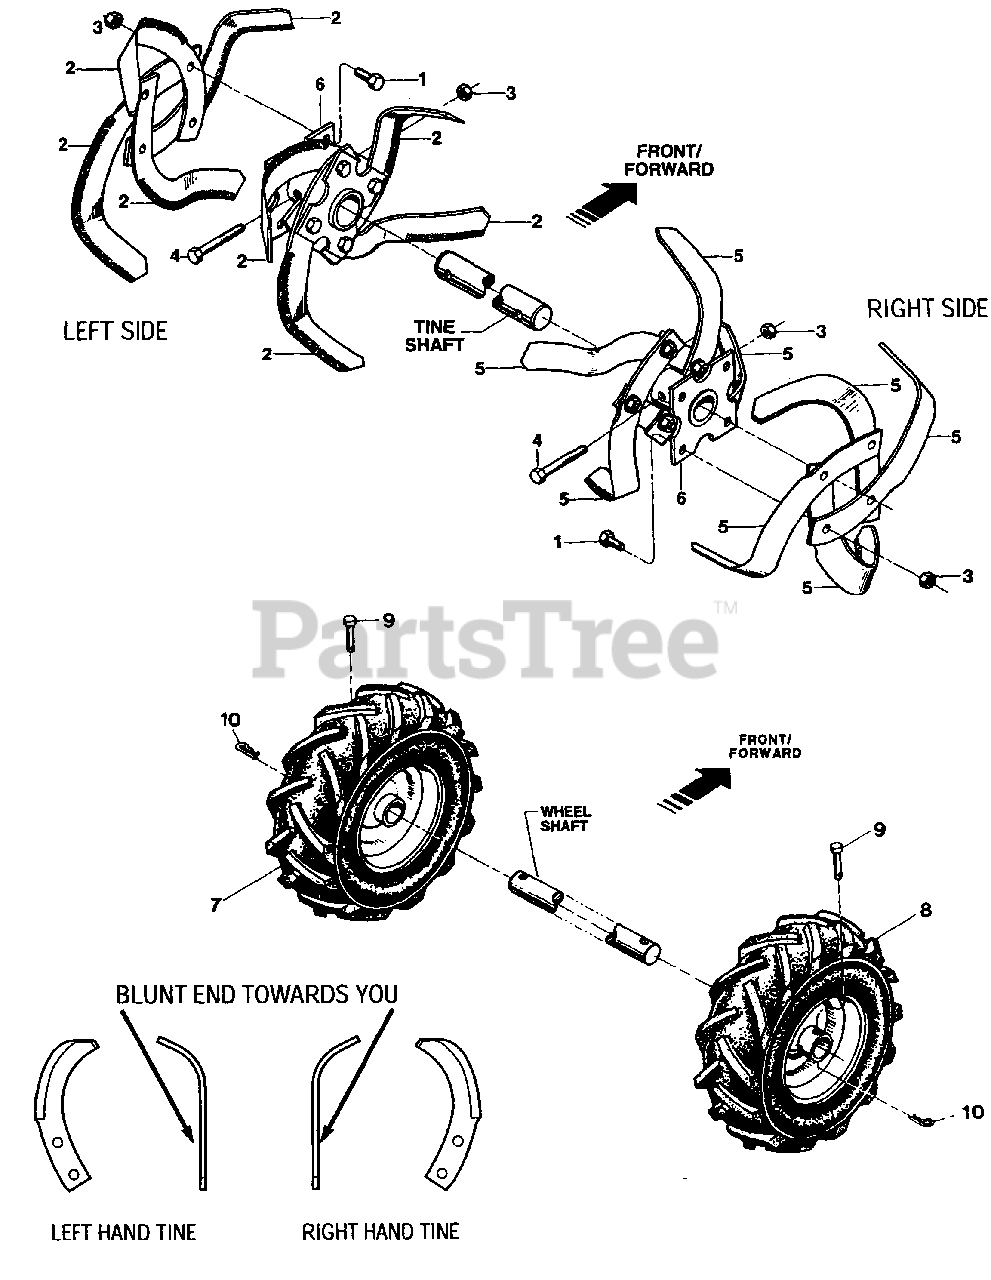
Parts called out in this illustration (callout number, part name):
1	Hex Screw, 3/8-16 x 1, Grade 5, Tine Mounting
2	Bolo Tine-Single, Right Hand tine
3	Hex Locknut, 3/8-16
4	Hex Screw, 3/8-16 x 1-3/4
5	Bolo Tine-Single, Left Hand tine
6	Tine Holder
7	Wheel & Tire Assy-Left Side
8	Wheel & Tire Assy-Right Side
9	Clevis Pin - .312" x 1-3/4
10	Hair Pin Cotter
